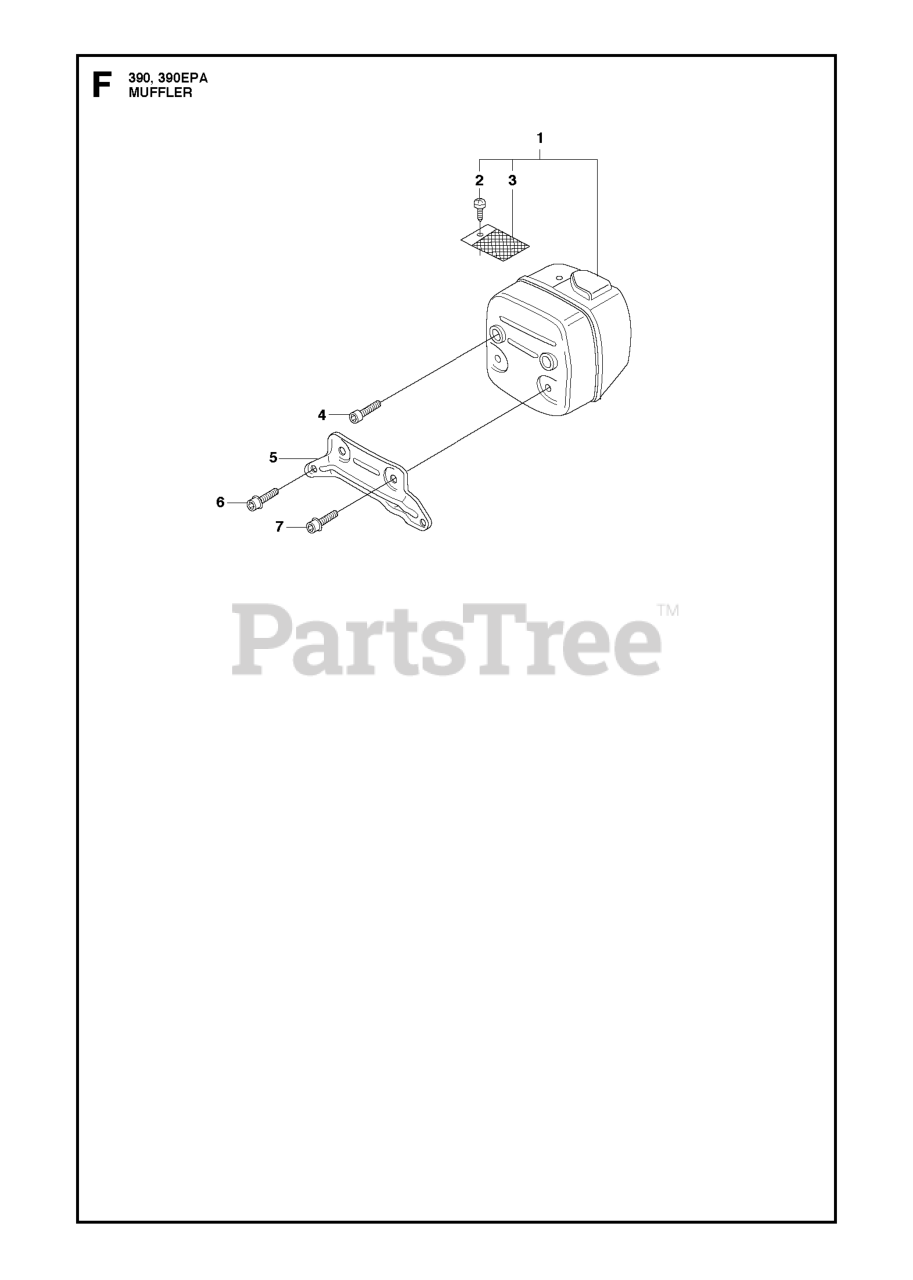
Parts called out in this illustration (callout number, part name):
1	MUFFLER ASSY
1	RP MUFFLER ASSY
4	SCREW MC6S 6X20
5	RP SUPPORT
